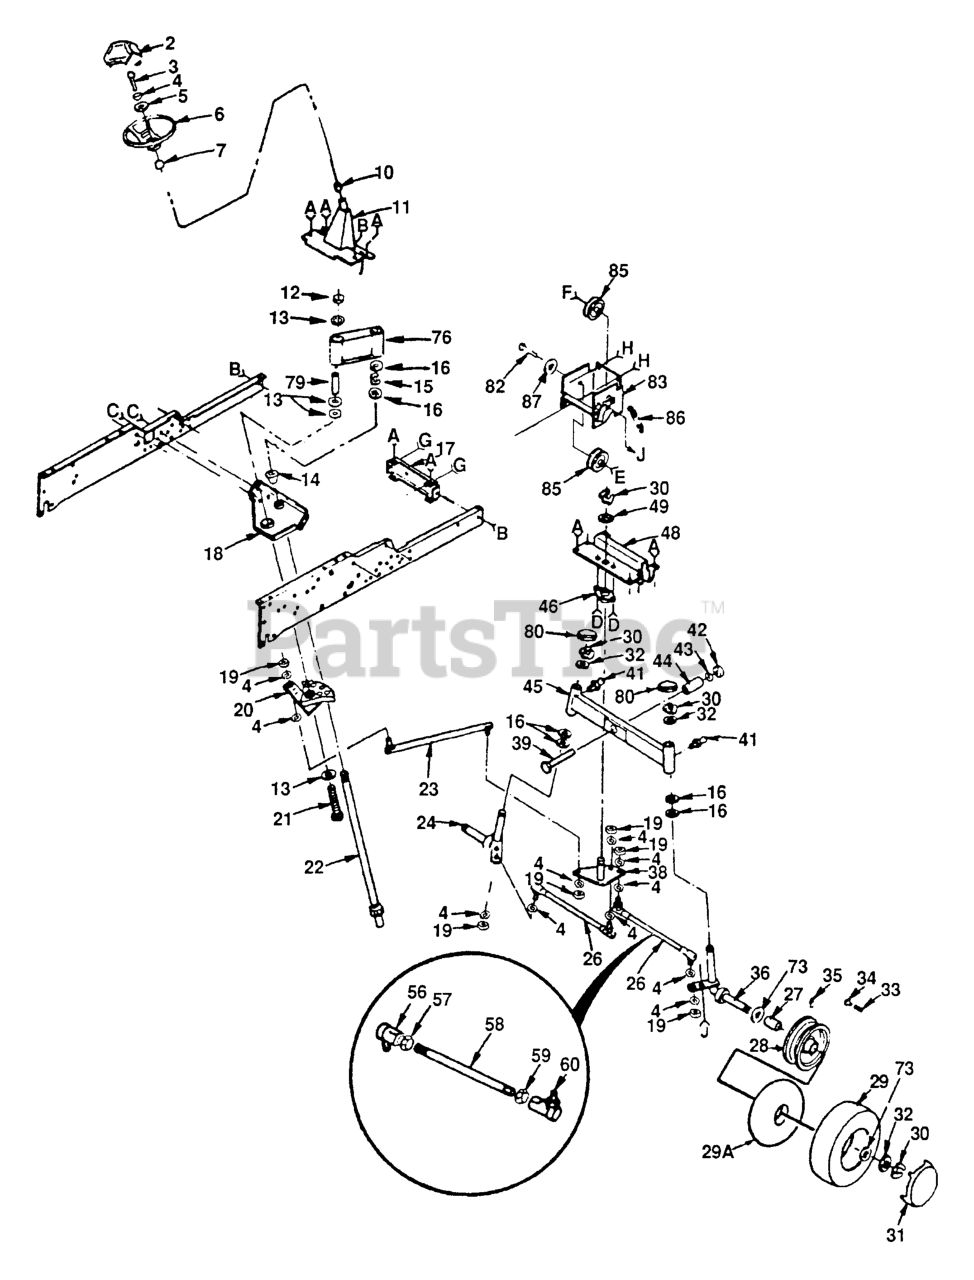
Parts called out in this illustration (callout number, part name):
2	INSERT,STR WHEEL
3	BOLT
4	WASHER, LOCK 3/8
5	WASHER T
6	STEERING WHEEL
7	ADAPTER LT
11	SUPPORT ASSY T
12	NUT LTV
13	WASHER GT
14	BEARING-FLANGE GT
16	THRUST WASHER
17	FRAME BRACKET GT
18	BRACKET ASSY GT
19	NUT
21	Bolt, Hex 1/2-13 x 5 Grade 5
22	SHAFT STEERING GT
23	DRAG LINK T
24	SPINDLE LH
26	DRAG LINK
27	BEARING.FLANGE
28	RIM ASSY 8" FRT
29	TIRE HEAVY DUTY
29A	TUBE.16X6.5/7.5-8
31	CAP,HUB REAR
34	VALVE STEM LT
35	FITTING LT.
36	SPINDLE RH
38	BELLCRANK T
39	Bolt, Hex 5/8-11 x 2-3/4 Grade 5
41	ZERK M
43	Washer, Lock 5/8
44	TUBE-PIVOT AXLE T
45	FRONT AXLE T
46	BELL CRANK BUSH T
48	AXLE BRACKET GT
49	Washer 29/32 x 1-1/4 x 16 Gauge
56	JOINT TIE ROD
80	CAP.SPINDLE.BLACK
82	BOLT
83	IDLER BRKT T
85	IDLER-INSIDE T
87	WASHER T
